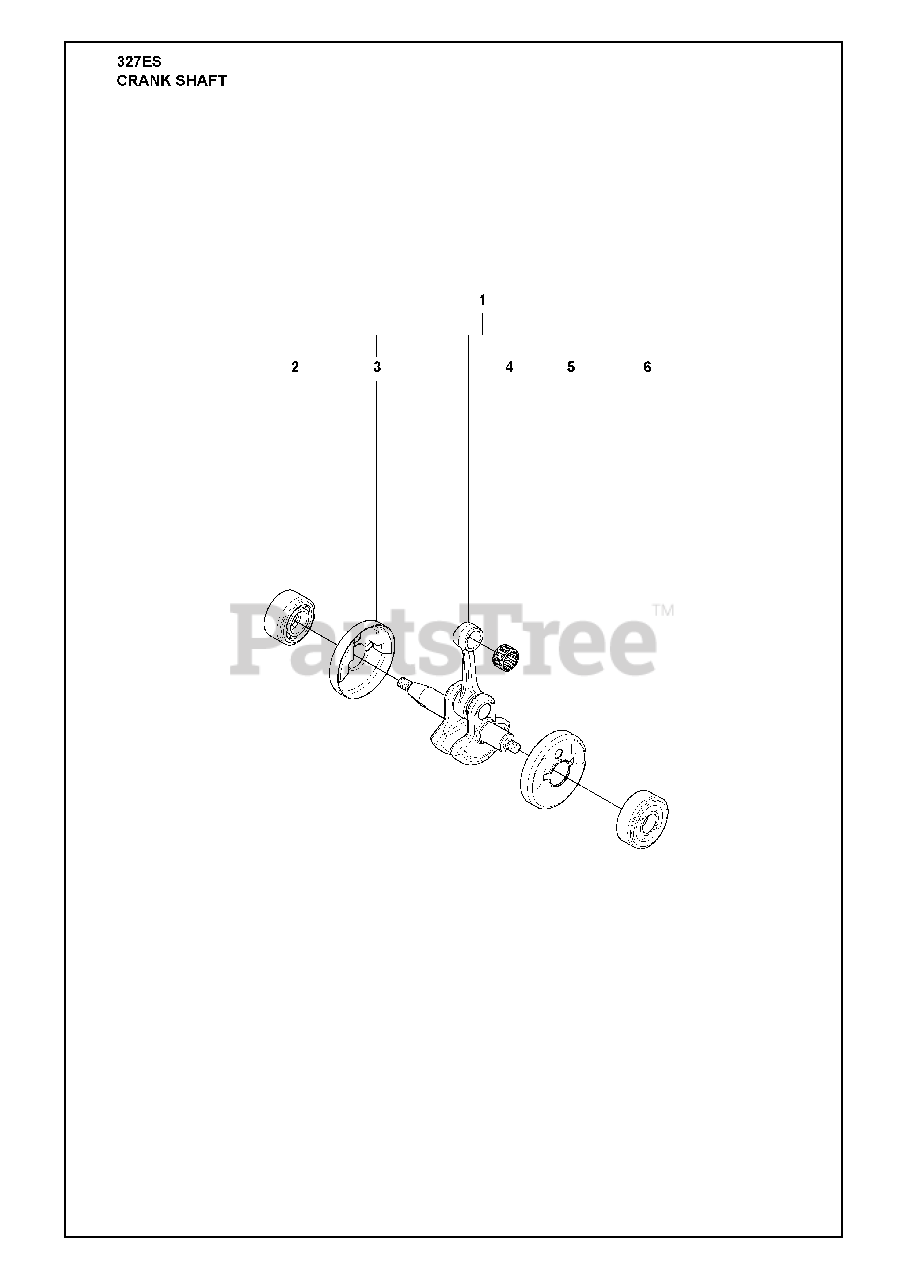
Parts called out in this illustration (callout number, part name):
1	CRANKSHAFT
2	BEARING CAP
6	BEARING CAP
